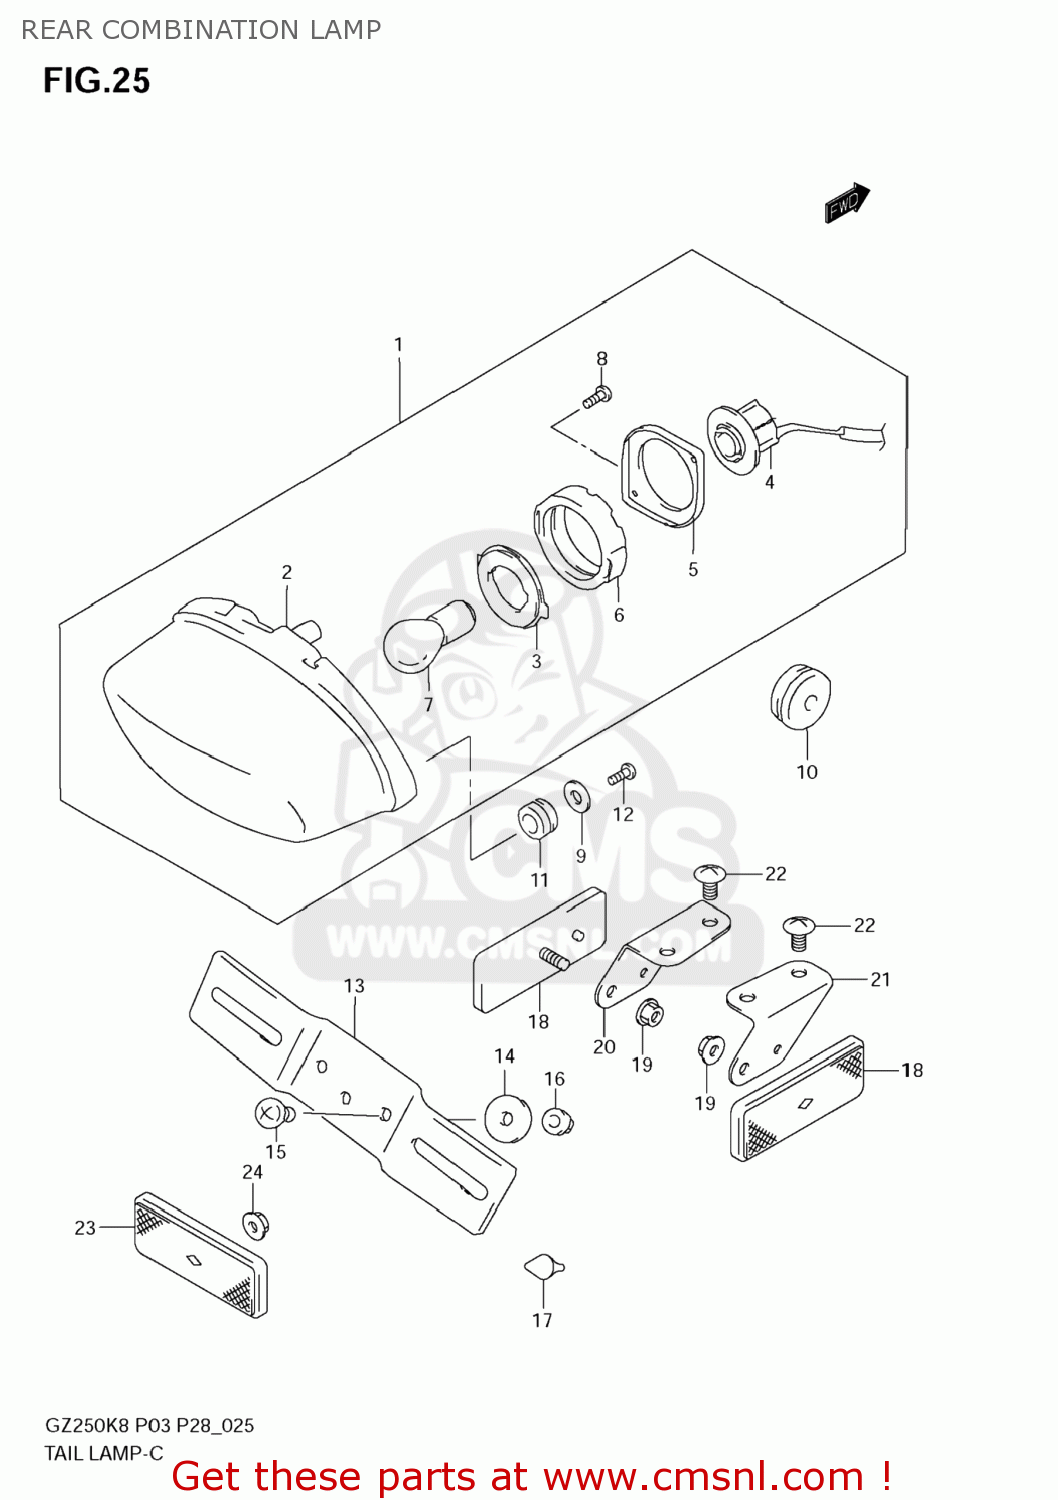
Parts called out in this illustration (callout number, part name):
1	LAMP ASSY,RR COMBINATION
2	LAMP UNIT
3	PLATE NO.1
4	SOCKET & CORD
5	PLATE NO.2
6	CUSHION
7	BULB(12V21/5W)
8	SCREW
9	WASHER(5.5X20X1.2)
10	GROMMET
11	CUSHION
12	SCREW
13	BRACKET,LICENSE PLATE
14	WASHER(6.5X20X1.6)
15	SCREW
16	NUT
17	CUSHION
18	REFLECTOR ASSY,RR
19	NUT
20	BRACKET,RR SIDE RR,L
21	BRACKET,RR SIDE RR,R
22	SCREW
23	REFLECTOR ASSY,RR
24	NUT
